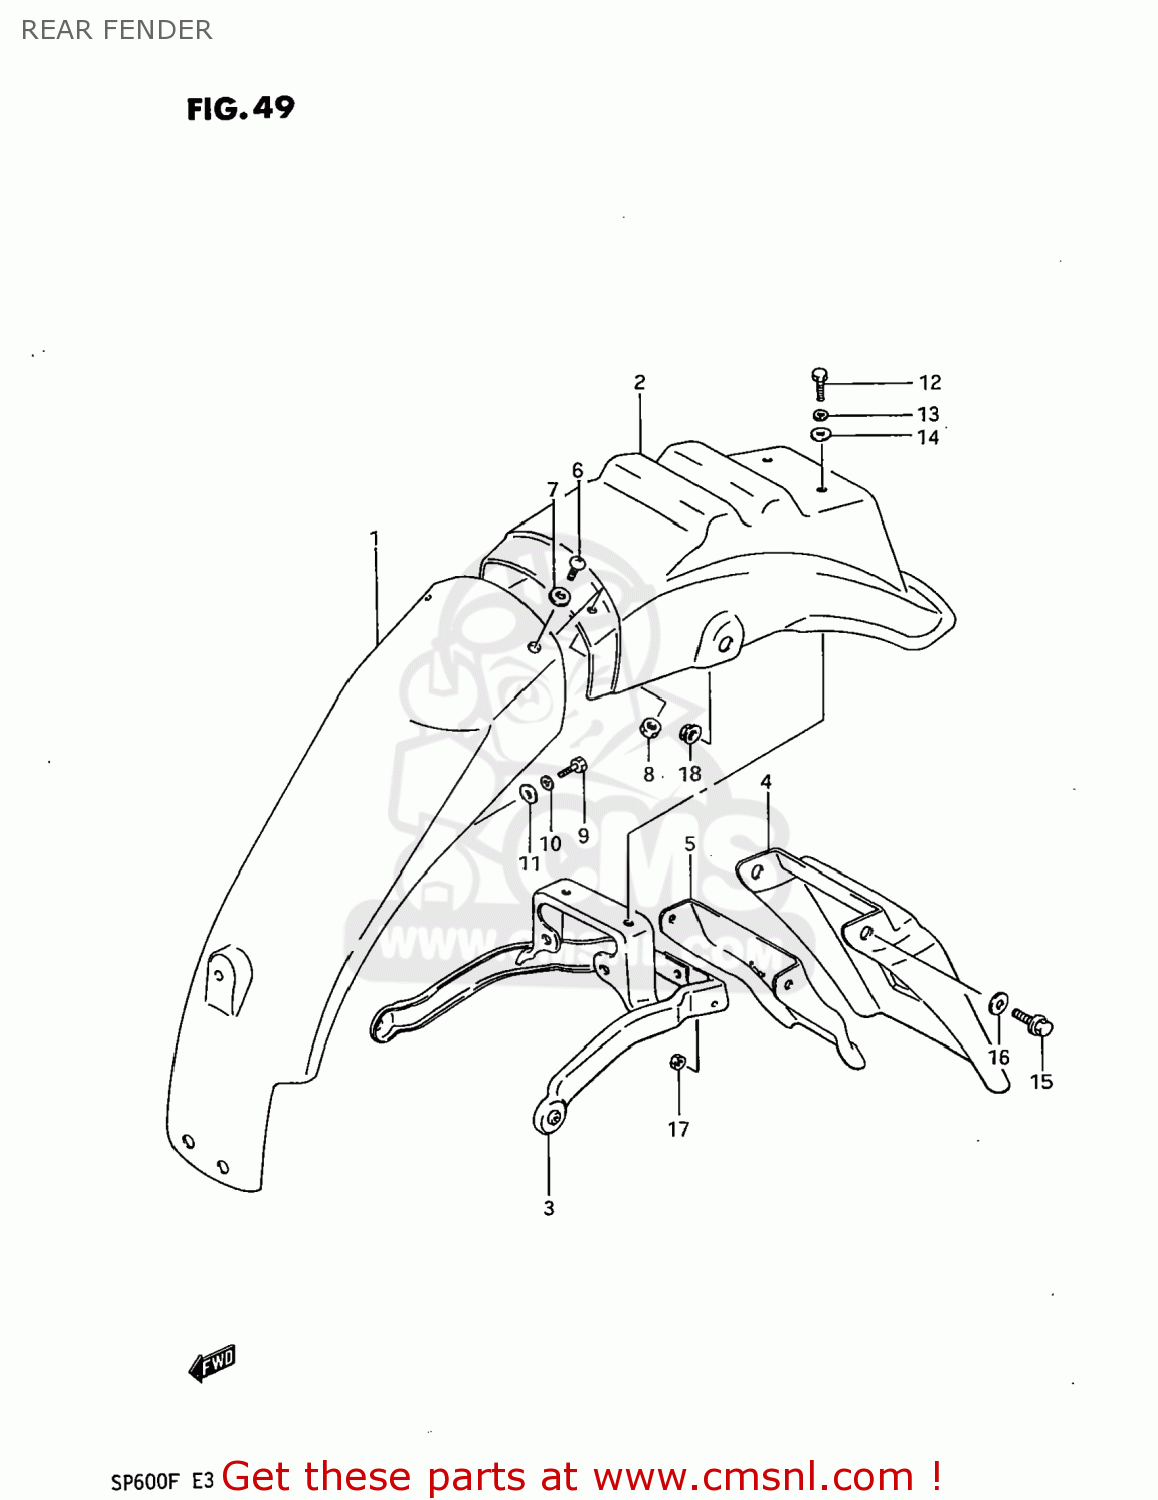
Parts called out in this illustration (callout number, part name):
1	BODY,REAR FENDER,FRONT
2	FENDER,REAR
3	REINFORCEMENT,REAR FENDER
4	EXTENSION,REAR FENDER
5	REINFORCEMENT,REAR FENDER EXTENSION
6	SCREW M5X12 DIN 7985/N
7	WASHER
8	NUT 8MM
9	BOLT 6X16
10	WASHER,LOCK
11	WASHER
12	BOLT
13	WASHER,LOCK
14	WASHER
15	BOLT
16	WASHER
17	NUT
18	NUT
